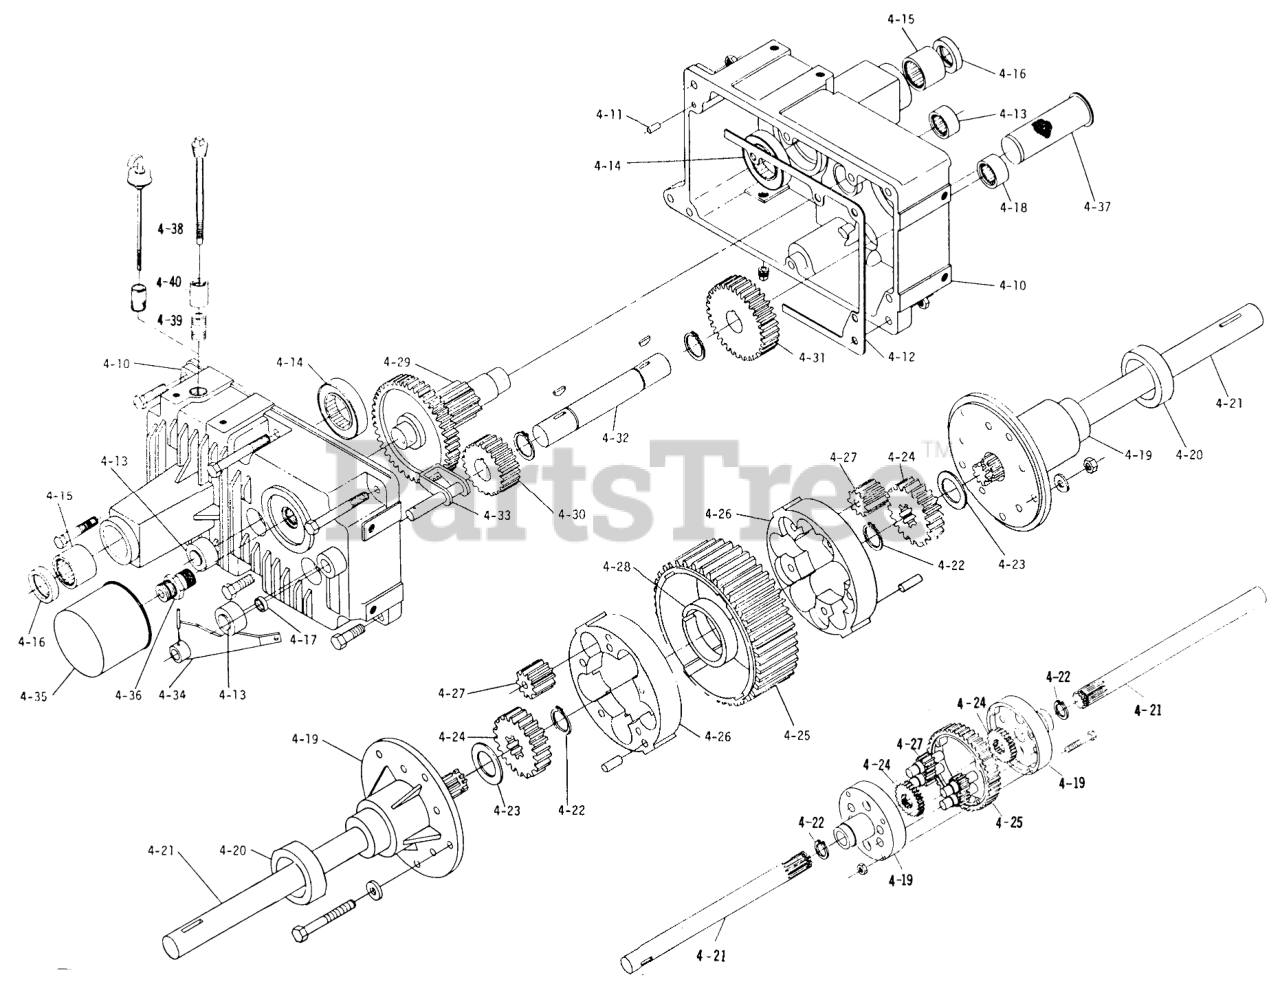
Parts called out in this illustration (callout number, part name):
4-10	Case RH
4-11	PIN-DOWEL
4-12	GASKET
4-13	BEARING-NEEDLE
4-14	BALL BRG 1 1/2 I.D.
4-15	Bearing-Axle
4-16	SEAL-OIL
4-17	SEAL BRAKE SHAFT
4-18	NEEDLE BEARING
4-19	End Cap-RH
4-21	Axle, R.H.
4-22	SNAP RING
4-23	THRUST WASHER
4-24	SIDE GEAR
4-25	Gear-Ring
4-26	Body
4-27	PINION
4-28	Spring
4-29	Gear
4-30	GEAR
4-31	Gear-33T
4-32	SHAFT GEAR
4-33	Assy.-Park Brake
4-34	Assy. Lever-Brake
4-35	Filter
4-36	FITTING
4-37	Strainer
4-38	Dipstick
4-39	Nipple
